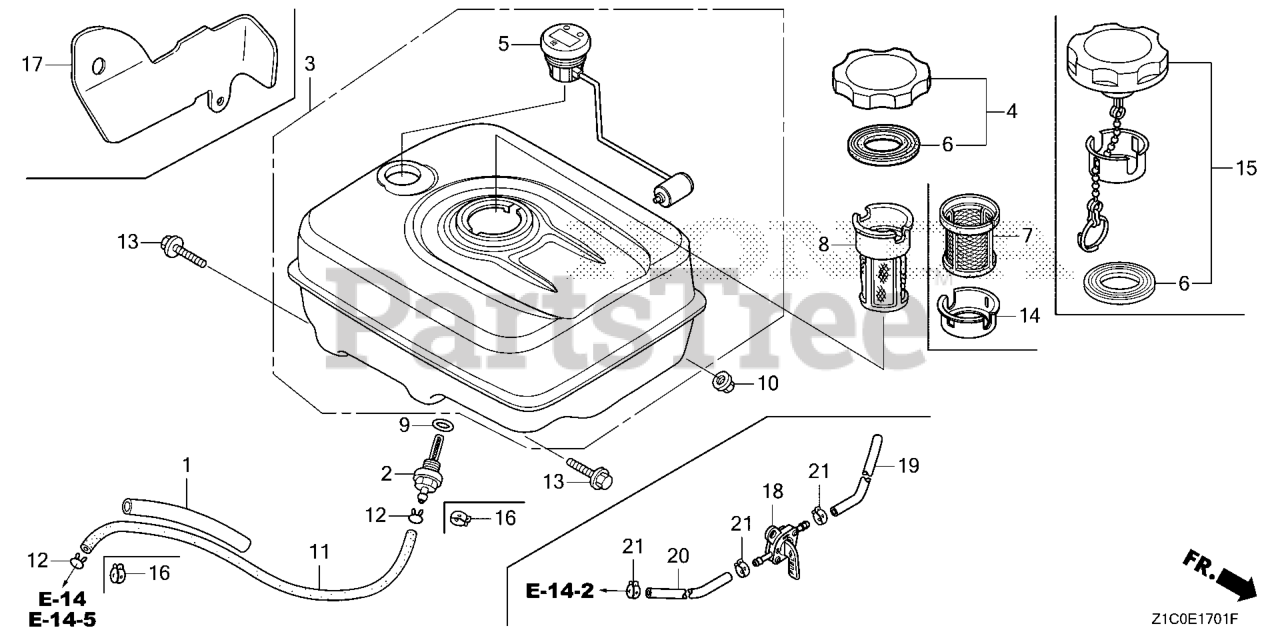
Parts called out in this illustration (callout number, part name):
2	JOINT, FUEL TANK
3	TANK ASSY., FUEL *NH31* (GAUGE) (MCKINLEY WHITE)
3	TANK ASSY., FUEL *NH1* (GAUGE) (BLACK)
5	GAUGE ASSY., FUEL
6	GASKET, FUEL FILLER CAP
6	GASKET, FUEL FILLER CAP (39X62X3) (TOUYOUSYA)
7	FILTER, FUEL (FROM 1204807)
9	O-RING (14MM) (ARAI) Use up to Engine SN 2949254.
10	NUT, FLANGE (8MM)
13	BOLT, FLANGE (8X25)
15	CAP, FUEL FILLER
16	CLIP, TUBE (D8)
18	PETCOCK ASSY. (DRAIN)
19	TUBE, FUEL (4.2X110) (FKM)
20	TUBE, FUEL (4.2X120) (FKM)
21	CLIP, TUBE (D8)
